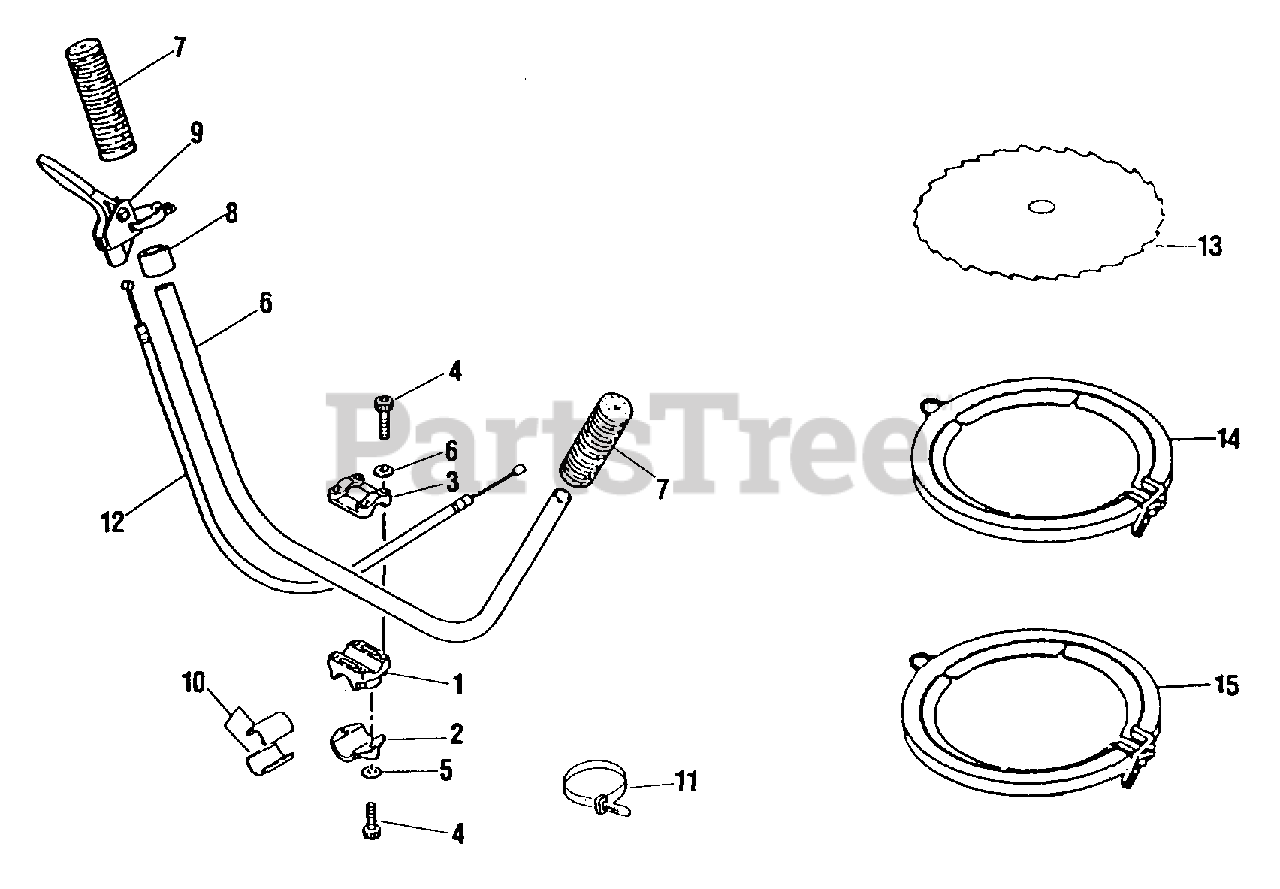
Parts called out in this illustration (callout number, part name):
1	BRACKET, HANDLE
2	CAP - LOWER
3	CAP - UPPER
4	SCREW - 5X25
5	WASHER - 5
6	HANDLE
7	GRIP, HANDLE
8	COLLAR
9	THROTTLE LEVER ASSY
10	SPACER, HANDLE
11	CLAMP
12	CABLE, THROTTLE
13	BLADE - 30 TOOTH -- 8" (20cm)
14	COVER, BLADE - 8" (20cm)
15	COVER, BLADE - 9" (22cm)
